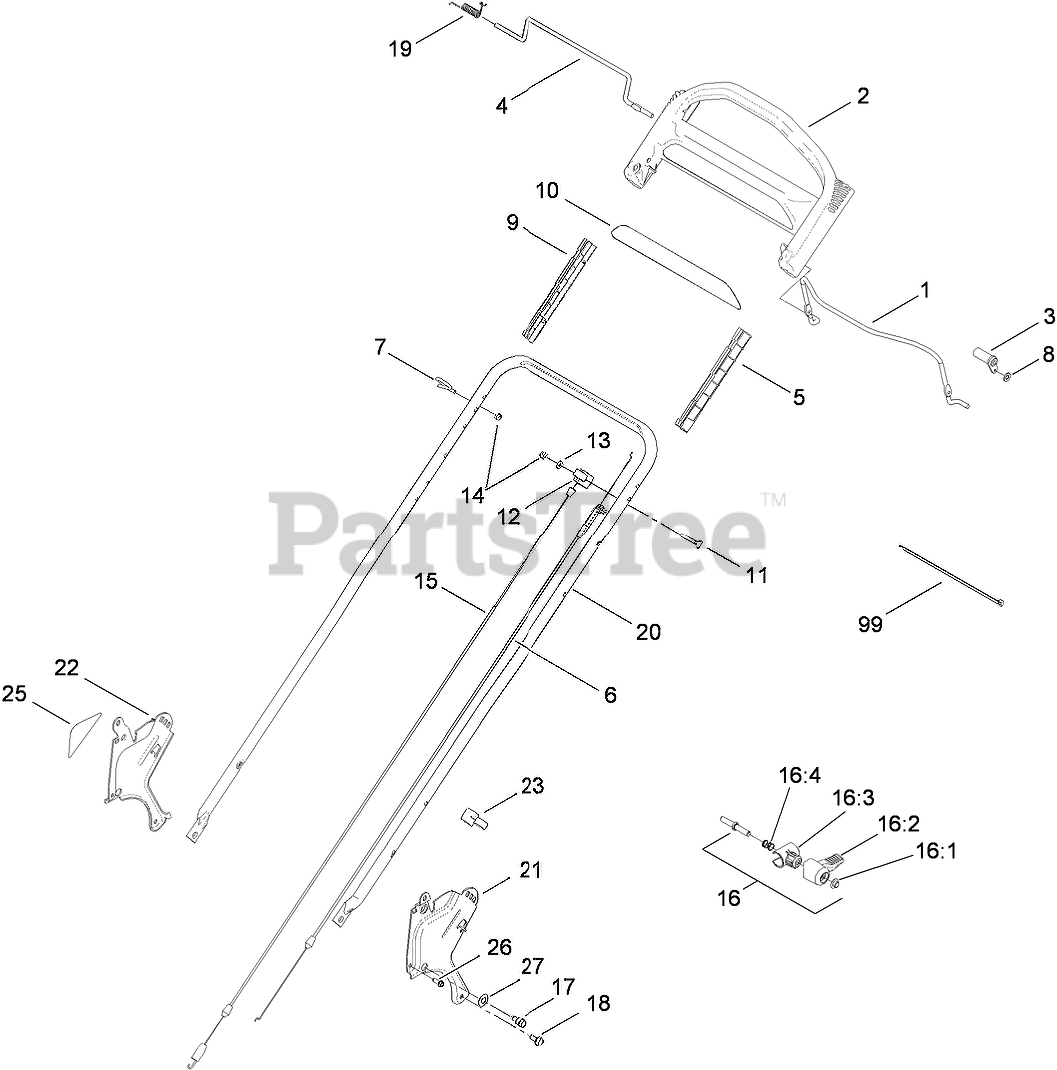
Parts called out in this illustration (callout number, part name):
1	Bail-Brake
2	HANDLE-CONTROL
3	LEVER-TRACTION
4	BAR-CONTROL, TRACTION
5	GUIDE-LH
6	CABLE-BRAKE
7	GUIDE-ROPE
8	WASHER-PLAIN
9	GUIDE-RH
10	DECAL-HANDLE
11	SCREW
12	ANCHOR-CABLE
13	WASHER-FLAT
14	NUT-LOCK, NI
15	CABLE-TRACTION
16	QUICK RELEASE ASM
16:1	NUT-PUSH
16:2	LEVER
16:3	ANCHOR-SPRING
16:4	SPRING-COMPRESSION
17	BOLT-SHOULDER
18	SCREW-HWHTF
19	Spring-Torsion
20	HANDLE
21	BRACKET-HANDLE, LH
22	BRACKET-HANDLE, RH
23	Guide-Cable
25	DECAL-INSTRUCTION
26	SCREW-HWHTF
27	WASHER-SPRING, CONICAL
99	TIE-CABLE
